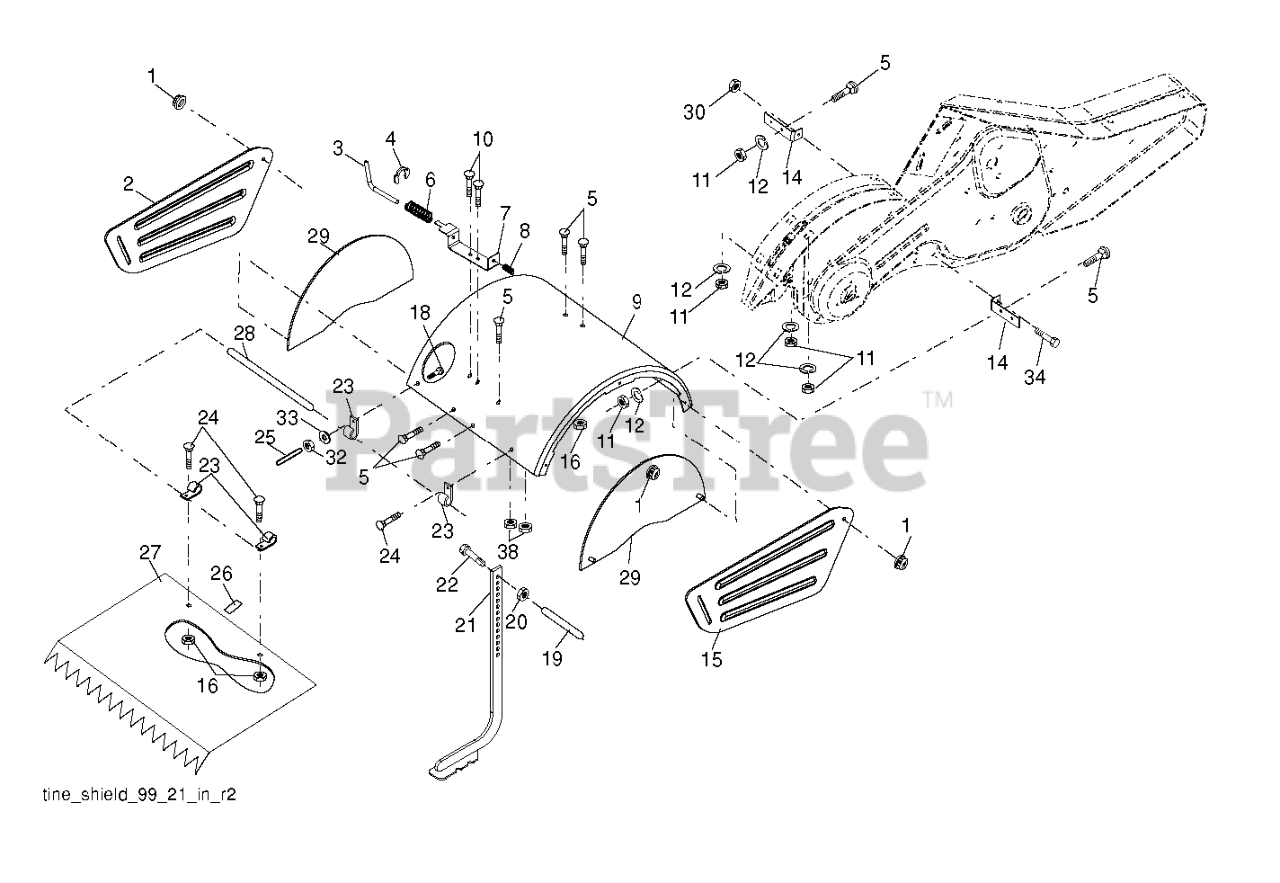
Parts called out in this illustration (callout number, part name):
1	NUT LOCK HEX FLANGE 5/16-18
2	TINE SHIELD
3	STAKE PIN TI
4	RING, KLIP
5	BOLT, RDHD SQNK 5/16-18 X 3/4
7	BRACKET.LATCH.STAKE.3.20.BLACK
8	SPRING CRT
9	SHIELD TINE
12	WASHER.LOCK.HVY.HLCL.SPR.5/16
14	BRACKET.TINE.SHIELD.TILLER
15	SHIELD
16	NUT T
20	NUT.HEX.3/8-16UNC
21	STAKE.ASM.DEPTH
22	BOLT.375-16
25	VINYL CAP TI
26	PAD IDLER TI
27	SHIELD.LEVELING.21".ORANGE
28	PIN, HINGE
29	SHIELD, SIDE
30	LOCKNUT-FLANGE 5/16-18
32	NUT
33	LOCKWASHER
34	Bolt Hex Flanged 5/16-18 Unc x 2
38	NUT
